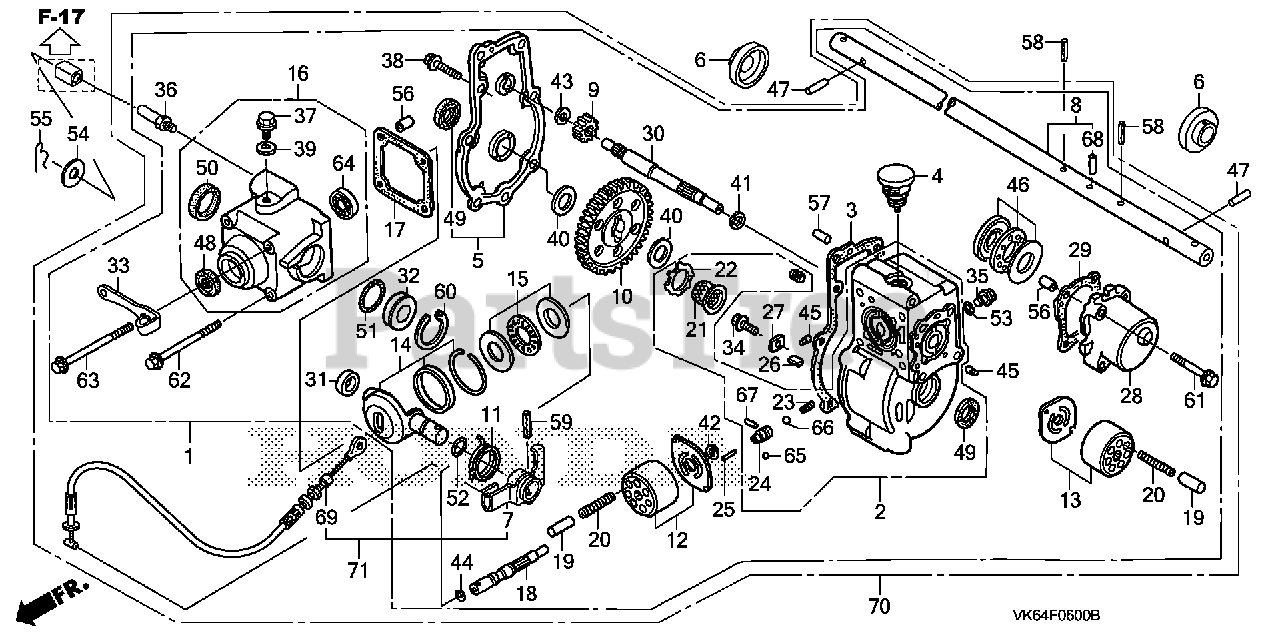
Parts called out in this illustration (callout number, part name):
1	TRANSMISSION ASSY.
2	CASE, TRANSMISSION
3	GASKET, TRANSMISSION CASE
4	CAP, OIL
5	COVER, TRANSMISSION
6	GUARD, GRASS
7	ARM, CONTROL
8	SHAFT, FINAL
9	GEAR, FINAL DRIVE (13T)
10	GEAR, FINAL DRIVEN (65T)
11	SPRING, CONTROL ARM RETURN
12	PLATE SET, PUMP CYLINDER
13	PLATE SET, MOTOR CYLINDER
14	BOWL SET, CONTROL
15	BEARING SET, THRUST NEEDLE
16	CASE SET, PUMP
17	GASKET, PUMP CASE
18	SHAFT, PUMP
19	PISTON, PUMP
20	SPRING, PISTON
21	FILTER, SUCTION
22	PLATE, FILTER
23	SPRING, RELIEF VALVE
24	BODY, NEUTRAL VALVE
25	NEEDLE A, NEUTRAL VALVE (22.4)
25	NEEDLE B, NEUTRAL VALVE (22.6)
25	NEEDLE C, NEUTRAL VALVE (22.8)
25	NEEDLE D, NEUTRAL VALVE (23.0)
25	NEEDLE E, NEUTRAL VALVE (23.2)
27	PLATE, MAGNET SETTING
28	CASE, MOTOR
29	GASKET, MOTOR CASE
30	SHAFT, MOTOR
31	BUSH, CONTROL BOWL (A)
32	BUSH, CONTROL BOWL (B)
33	HOLDER, CONTROL CABLE
34	BOLT, FLANGE (6X18)
35	BOLT A, PLUG
36	BOLT, GUIDE
37	BOLT, SEALING (8MM)
38	BOLT, FLANGE (6X21)
39	WASHER, SEALING (8X16X1.6)
40	WASHER (15X24X3.2)
41	WASHER, THRUST (10.2X16X1)
42	WASHER, THRUST (13X8.3X1.6)
43	WASHER, THRUST (8.6X13X0.6)
44	CLIP B, BEARING
45	PIN, DOWEL (3X5.8)
46	BEARING, THRUST BALL
47	ROLLER (5X23.8)
48	OIL SEAL (10X20X5)
49	OIL SEAL (15X24X5)
50	PLUG, SEAL (22X7)
51	O-RING (25X2.4)
52	O-RING (11.8X1.9)
53	O-RING (6.8X1.9)
54	WASHER, PLAIN (10MM)
55	PIN, LOCK (10MM)
56	PIN A, DOWEL (8X10)
57	PIN C, DOWEL (4X6.5)
58	PIN, SPRING (4X22)
59	PIN, SPRING (5X20)
60	CIRCLIP (INNER) (30MM)
61	BOLT, FLANGE (6X32) Use up to Frame SN 1008045.
62	BOLT, FLANGE (6X60)
63	BOLT, FLANGE (6X65)
64	BEARING, RADIAL BALL (6000)
65	BALL, STEEL (#5) (5/32)
66	BALL, STEEL (#8) (1/4)
67	ROLLER (4X19.8)
68	ROLLER (6X22.4)
69	CABLE, CHANGE
